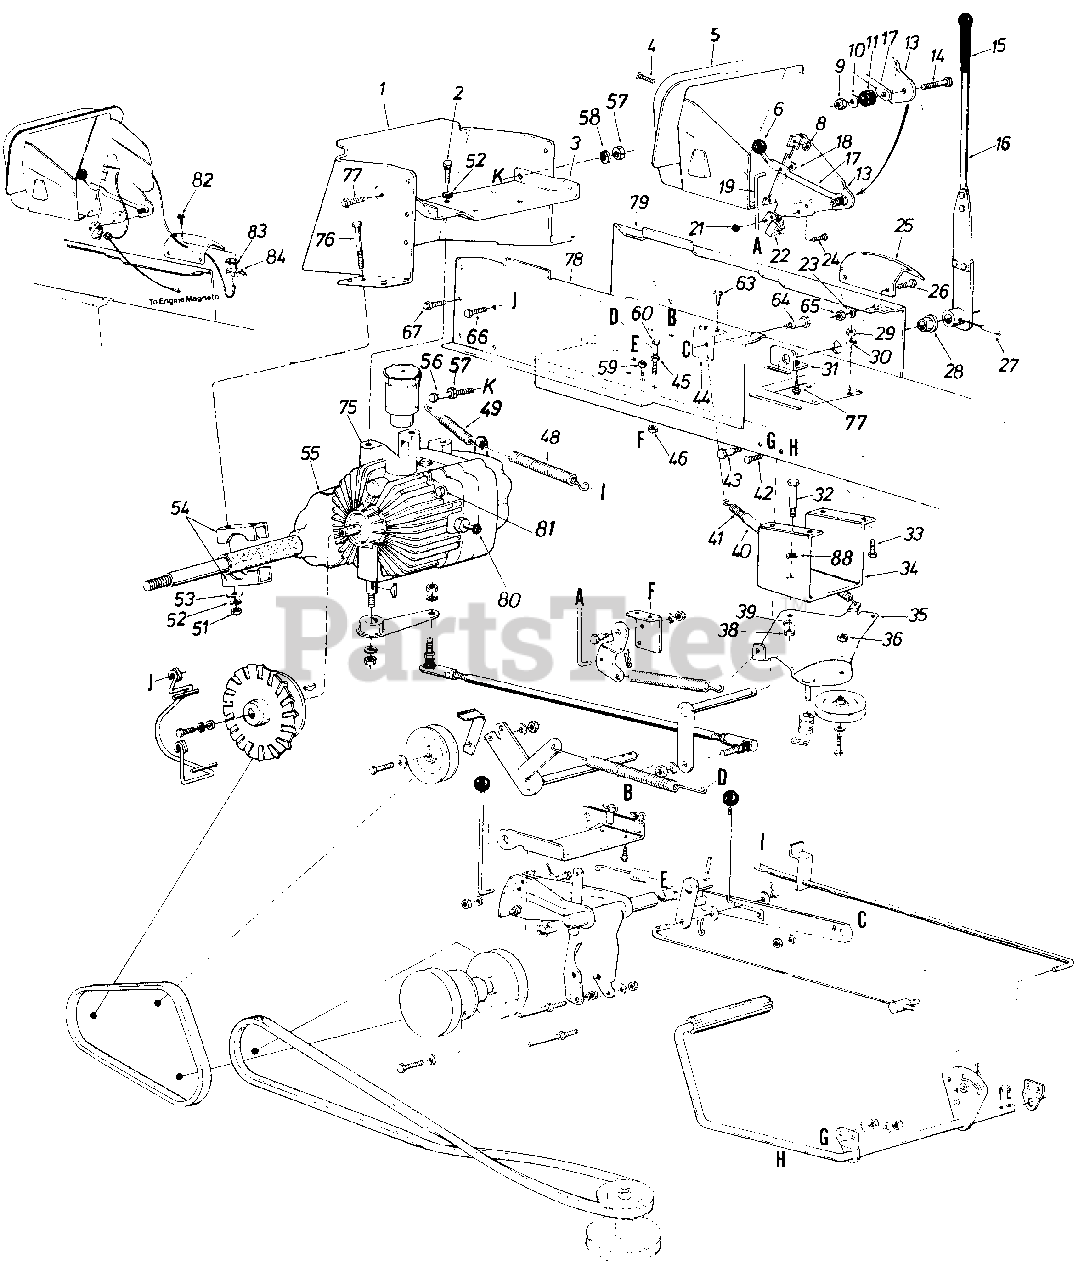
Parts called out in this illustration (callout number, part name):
1	Hitch Plate
2	Hex Bolt 3/8-16 x .75" Lg.
3	Rear Axle Support Brkt.
4	Truss Mach. Scr. 1/4-20 x .50" Lg.
5	Dash Panel Ass'y.
6	Knob Blade Clutch
8	Hex Sems Nut 1/4-20 Thd.
9	Hex Cent. L-Nut 1/4-20 Thd.
10	Fl-Wash. .28" I.D. x .74" O.D. x .063
11	Rubber Wash. .33" I.D. x .87" O.D. x.30
13	Deck Clutch Cont. Brkt.
14	Hex Bolt 1/4-20 x 1.251' Lg.
16	Control Arm Ass'y.
17	Blade Clutch Lever
18	Push Nut 1/4" O.D. Rod
19	Deck Control Rod
21	Hex Nut #10-24 Thd.
22	Safety Switch
23	L-Wash. 5/16" I.D.
24	Truss Mach. Scr. #10-24 x .50" Lg.
25	Speed Control Bracket
26	Hex Bolt 5/16-18 x .62" Lg.
27	Spring Pin Spiral 1/4" Dia. x 1.5" Lg.
28	Hex Flange Brg.
29	Hex Nut 5/16-18 Thd.
30	L-Wash. 5/16" I.D.
31	Speed Control Shaft Brkt.
32	Shld. Scr. .437" Dia. x .162" Lg.
33	Hex Bolt 5/16-18 x 1.00" Lg.
34	Idler Support Brkt.
35	Idler Brkt. Ass'y.
36	Hex L-Nut 3/8-16 Thd.
38	Hex Nut 5/16-18 Thd.
39	L-Wash. 5/16" I.D.
40	Convoluted Conduit .50" I.D.
41	Ext. Spring .50" O.D. x 6.37" Lg.
42	Hex Bolt 3/8-16 x .62" Lg.
43	Shld. Scr. .50" Dia. x .395" Lg. (3/8-16)
44	Parking Brake Cam Mtg. Brkt.
45	Hex Nut 5/16-28 Thd.
46	Hex L-Nut 5/16-18 Thd.
48	Brake Tension Spring
49	Ext. Spring Brake Return
51	Hex Nut 3/8-16 Thd.
52	L-Wash. 3/8" I.D.
53	Fl-Wash. .390" I.D. x 1.00" O.D. x .125" Thk.
54	Rear Axle Bracket
55	Transaxle
56	Hex Bolt 1/4-20 x 2" Lg.
57	Hex Nut 1/4-20 Thd.
58	L-Wash. 1/4" I.D.
59	Hex Wash. Hd. Self-Tap Scr. 1/4-20 x .50" Lg.
60	Hex Bolt 5/16-18 x 1.50" Lg.
63	Hex Wash. Hd. Self-Tap Scr. 1/4-20 x .50" Lg.
64	Shld. Scr. .437" Dia. x .162" Lg.
65	Hex Nut 5/16-18 Thd.
66	Hex Wash. Hd. Scr. 3/8-16 x .50" Lg.
67	Hex Wash. Hd. Self-Tap Scr. 5/16-18 x .75" Lg.
75	Hydrostatic Pump Comp.
76	Hex Bolt 3/8-16 x 3.5" Lg.
77	Hex AB-Tap Scr. 5/16 x .75" Lg.
78	Side Panel Upper Frame R.H.
79	Side Panel Upper Frame L.H.
81	Socket Hd. Bolt 3/8-16 x 2.75" Lg.
82	Hex Wash. Hd. Scr. #8 x .50" Lg.
83	Insulator Nut Plate
84	Spring Switch
88	Wave Washer
